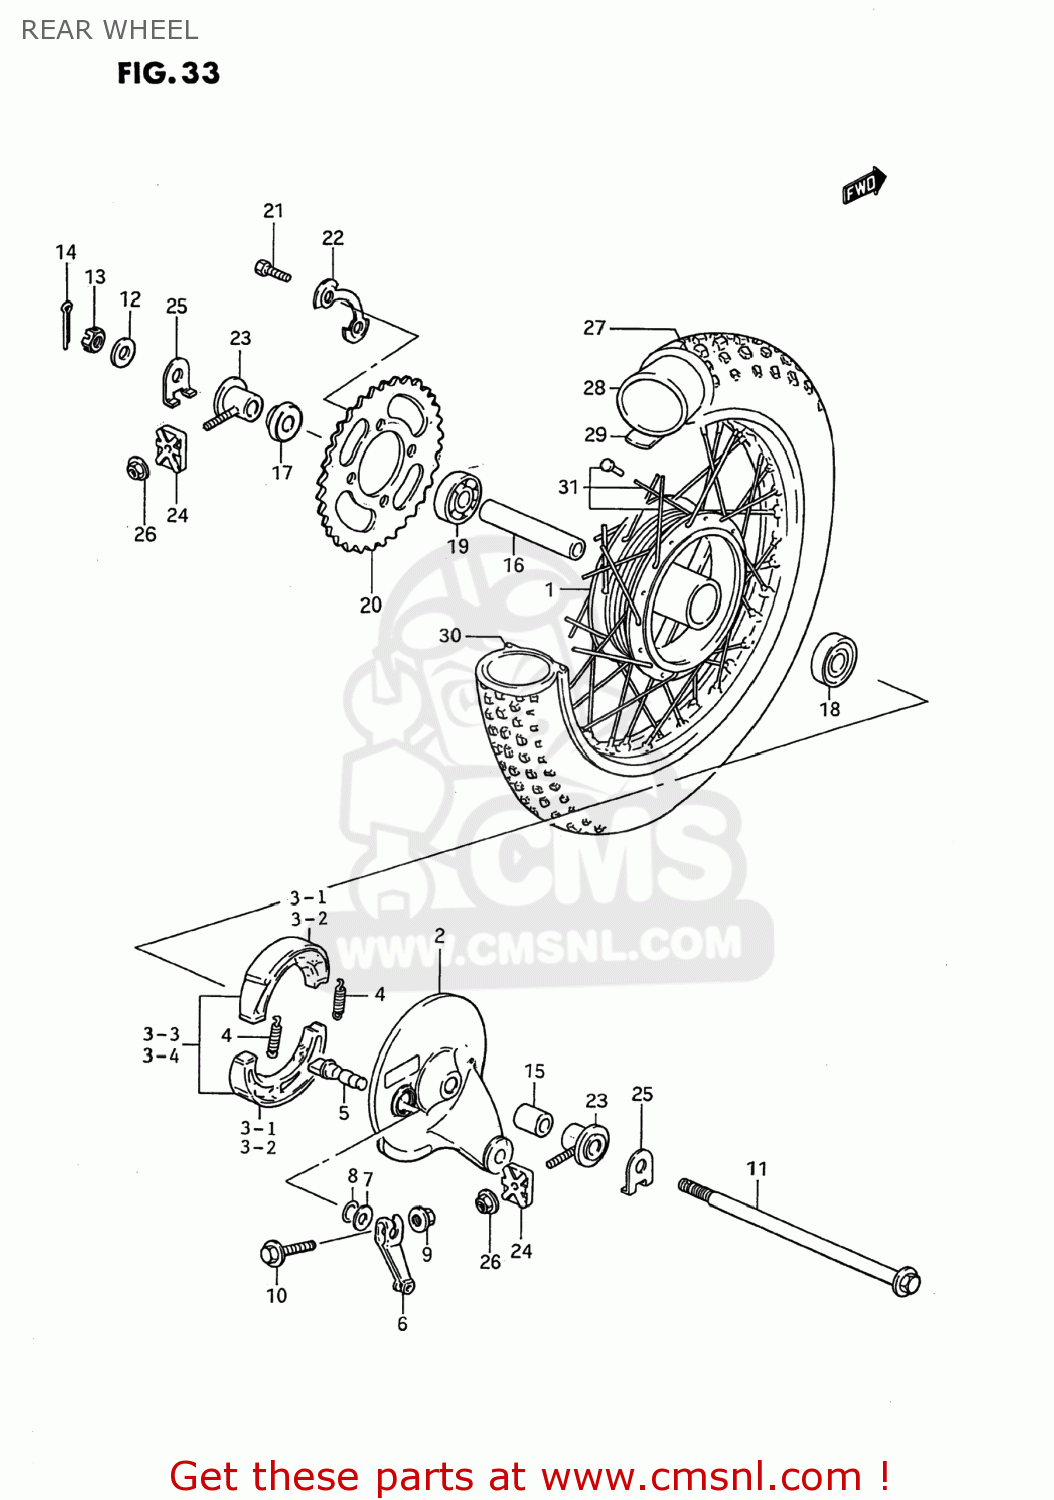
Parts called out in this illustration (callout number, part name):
1	HUB,RR
2	PANEL,RR BRAKE ANCHOR
3	SHOE,BRAKE
4	SPRING(L:35.8)
5	CAM,BRAKE
6	LEVER,RR BRAKE CAM
7	WASHER (14.5X22X1.6)
8	O-RING (D:2.4 ID:13.8)
9	NUT
10	BOLT
11	AXLE,RR
12	WASHER
13	NUT, REAR AXLE
14	COTTER PIN
15	SPACER(12.1X22X22)
16	SPACER(12.6X19X91)
17	SPACER,RR AXLE,L
18	BEARING
19	BEARING
20	SPROCKET,REAR
21	BOLT(8X25)
22	WASHER
23	ADJUSTER,CHAIN
24	PLATE,CHAIN ADJUSTER GUIDE
25	WASHER,CHAIN ADJUSTER
26	NUT
27	TIRE(3.00 12)
28	TUBE,INNER
29	PROTECTOR,INNER TUBE
30	RIM,RR WHEEL(1.60X12)
31	SPOKE ASSY,RR WHEEL
